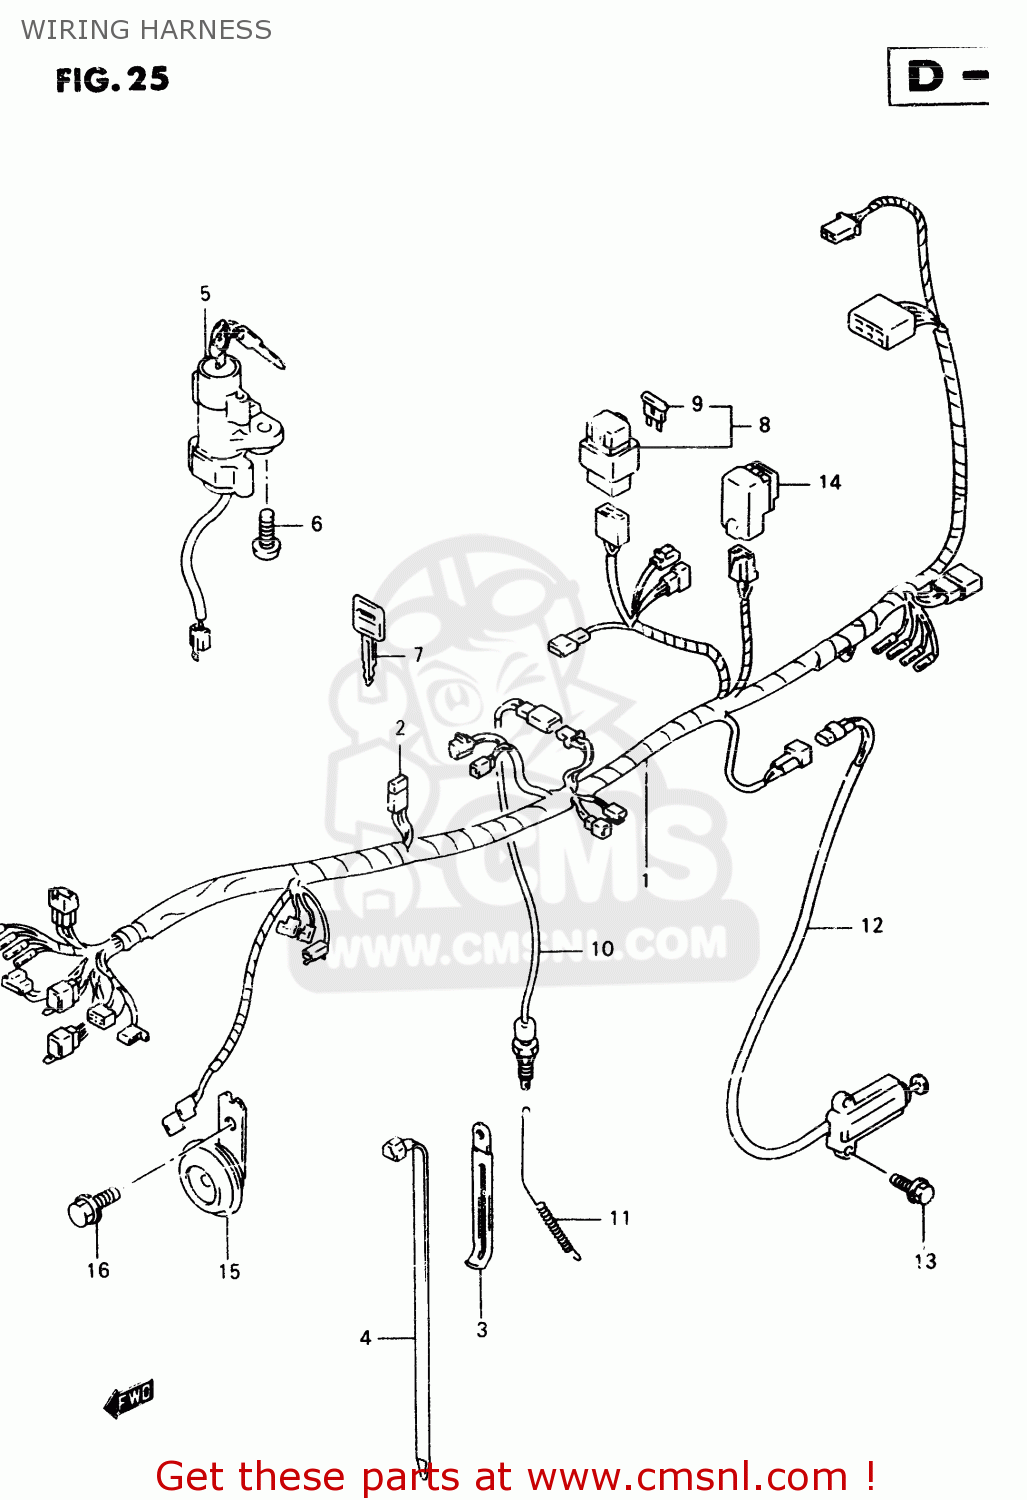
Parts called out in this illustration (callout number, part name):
1	HARNESS,WIRING
2	DIODE(STANLEY DE8804)
3	CLAMP(L:65)
4	CLAMP L:165
5	LOCK ASSY,STEERING
6	BOLT(8X20)
7	KEY,BLANK
8	BOX ASSY,FUSE
9	FUSE(15A)
10	SWITCH ASSY,STOP LAMP
11	SPRING
12	SWITCH ASSY,SIDE STAND
13	BOLT
14	RELAY ASSY
15	HORN ASSY
16	BOLT
